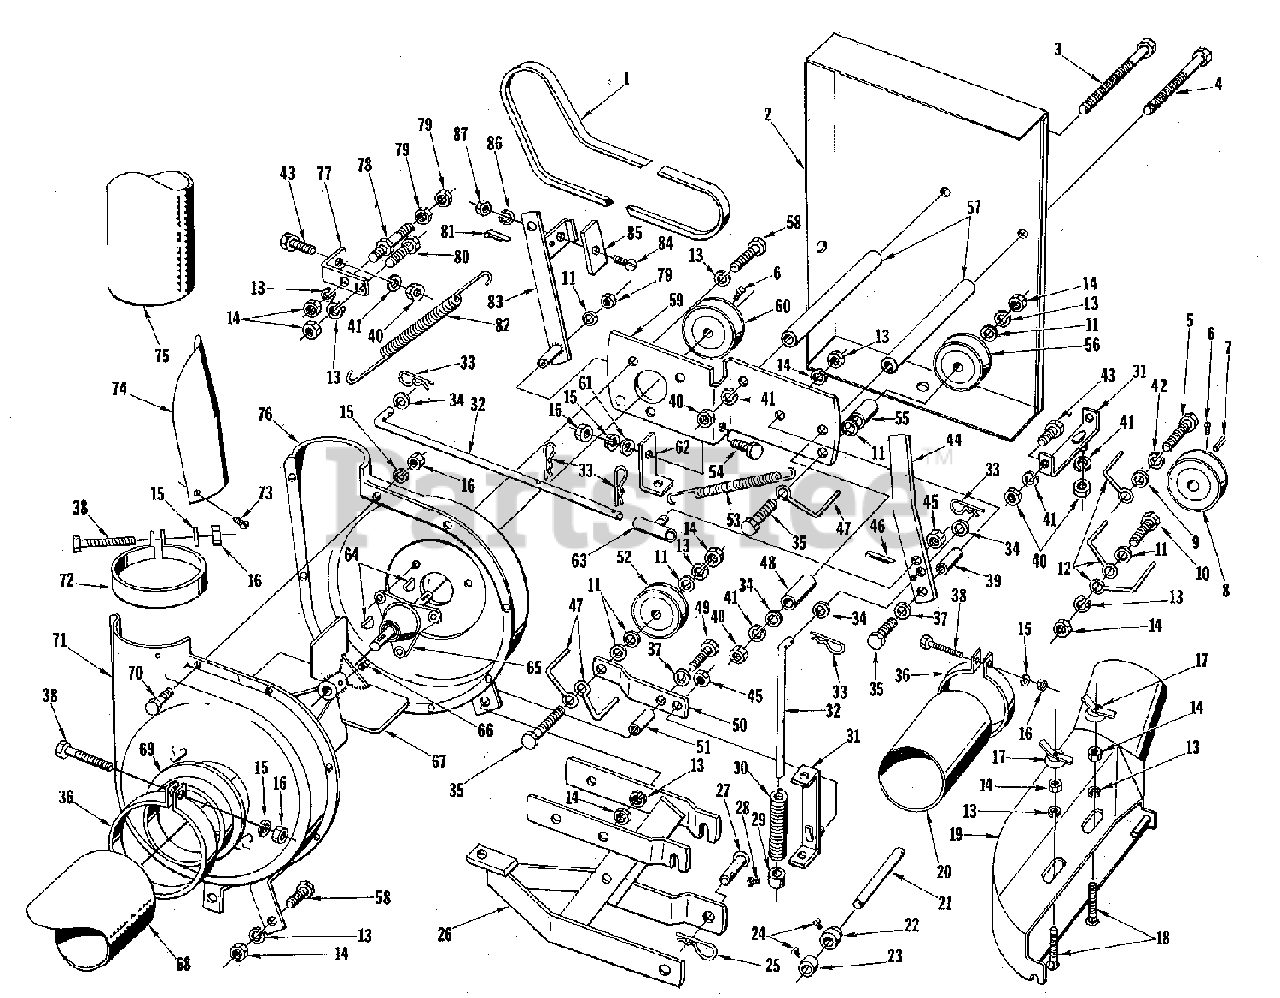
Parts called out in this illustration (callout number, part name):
1	BELT, "V", Drive
2	COVER, Belt Drive
3	SCREW, Cap, 5/16-18 x 2
4	SCREW, Cap, 5/16-18 x 4
5	SCREW, Cap, 7/16-14 x 1-1/4
6	SCREW, Set, 5/16-18 x 1/2 Square Head Cup Point
7	KEY, Parallel, Flat, 3/16 x 3/16 x 1
9	WASHER, Flat, 7/16
10	SCREW, Cap, 3/8-16 x 1-1/8
11	WASHER, Flat, 13/32 x 7/8
13	WASHER, Lock, 3/8
14	NUT, Hex, 3/8-16
15	WASHER, Lock, 1/4
16	NUT, Hex, 1/4-20
17	NUT ASSEMBLY
18	BOLT, Carriage
19	ADAPTER, Vacuum Collector
20	EXTENSION, Hose
24	SCREW, Set, 5/16-18 x 3/8
26	SUPPORT ASSEMBLY, Blower Housing
28	SCREW, Set, 1/4-20 x 5/16
30	SPRING, Compression
31	GUIDE ASSEMBLY, Rod
32	ROD, Control
34	WASHER, Flat, 11/32 x 7/8
35	SCREW, Cap, 3/8-16 x 1-1/2
37	WASHER, Flat, 13/32 x 1-1/2
38	SCREW, Machine, 1/4-20 x 2
39	SPACER, Pivot
40	NUT, Hex, 5/16-18
41	WASHER, Lock, 5/16"
42	WASHER, Lock, 7/16
43	SCREW, Cap, 5/16-18 x 3/4
45	NUT, Hex, Lock, 5/16-18
46	PIN, Cotter, 3/32 x 3/4
49	SCREW, Cap, 3/8-16 x 3
51	PIVOT, Idler Arm
53	SPRING, Tension
54	SCREW, Cap, 1/4-20 x 1
56	PULLEY, Idler
57	SPACER, Hood (R.H.)
58	SCREW, Cap, 3/8-16 x 1
59	BRACKET ASSEMBLY, Idler Support
61	WASHER, Flat, 1/4
62	CLIP, Baffle
63	GUIDE ASSEMBLY, Rod
64	KEY, Woodruff, 3/16 x 3/4
65	FLANGE ASSEMBLY, Shaft & Bearing
66	SCREW, Set, 5/16-18 x 5/16 Cup Point
67	FAN ASSEMBLY
68	HOSE, Intake
69	FLANGE, Hose
70	SCREW, Cap, 1/4-20 x 1/2
71	HOUSING ASSEMBLY, Inlet Half
73	SCREW, Self Tapping, #10 x 3/8
75	HOSE, Exhaust
76	HOUSING ASSEMBLY, Blower Half
77	BRACKET, Cover
79	NUT, Hex Lock, 3/8-16
80	SCREW, Cap, 3/8-16 x 1-1/4
81	PIN, Cotter, 3/16 x 1
82	SPRING, Tension
83	LEVER ASSEMBLY, Brake
84	SCREW, Machine, #10-24 x 5/8
85	BRACKE, Sheave
86	WASHER, Lock, #10
87	NUT, Hex, #10-24
